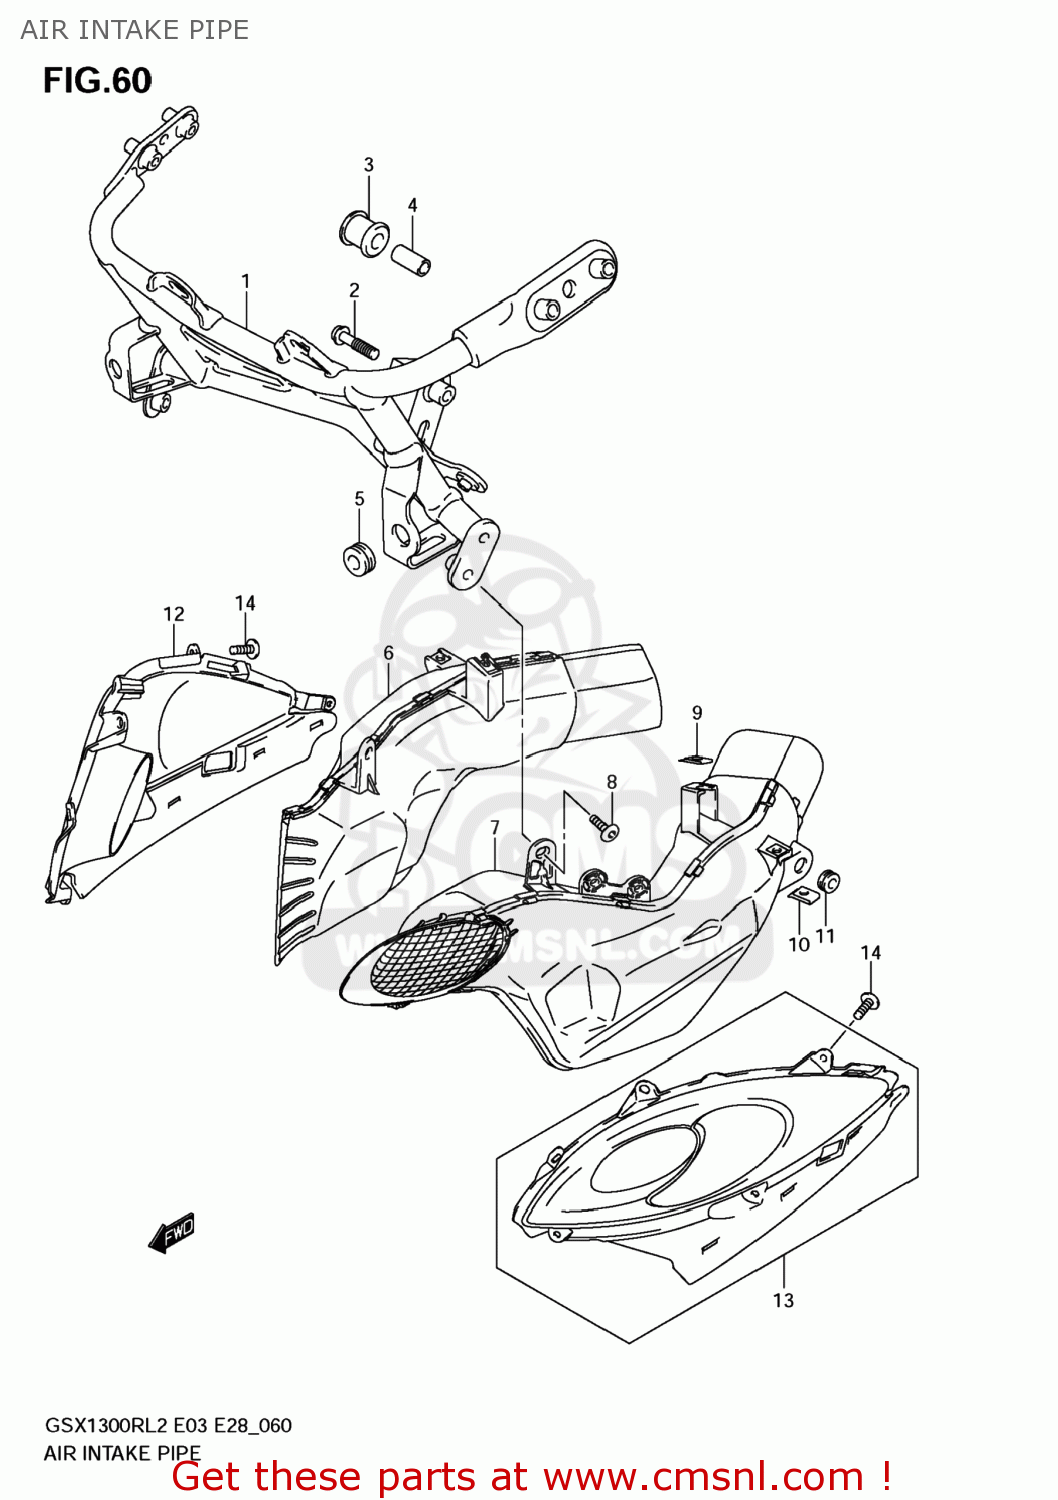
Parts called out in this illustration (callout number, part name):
1	BRACE,COWLING
2	BOLT(8X40)
3	CUSHION,COWLING BRACE
4	SPACER(8.6X12.2X26.5)
5	CUSHION
6	PIPE,AIR INTAKE,R
7	PIPE,AIR INTAKE,L
8	SCREW,INTAKE PIPE & BRACE
9	NUT,COWL
10	NUT
11	CUSHION
12	COVER,INTAKE,R
13	COVER,INTAKE,L
14	SCREW(5X16)
